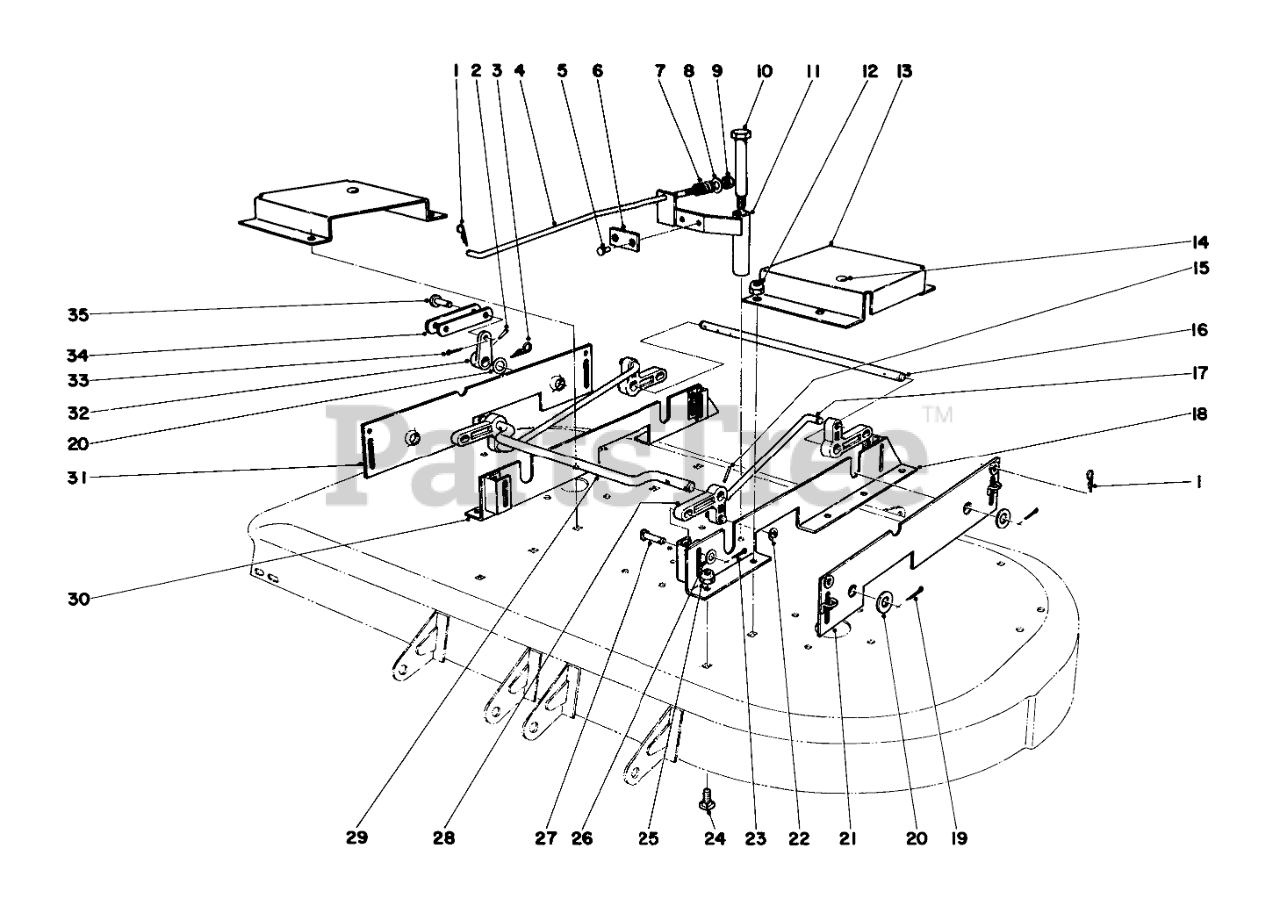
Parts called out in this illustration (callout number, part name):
1	PIN-COTTER, HAIR
2	Pin Drive
3	HAIRPIN COTTER
4	Brake Rod
6	BLADE BRAKE LINING
7	Spring
8	Washer
9	NUT-LOCK, CONE
10	Shoulder Bolt
11	a. Bracket
12	NUT-LOCK, CONE
13	Cover
14	Plug Button
15	PIN-SPRING
16	Rear Pivot Shaft
17	Lift Link
18	Bracket Assy. Lower
19	PIN-COTTER
20	Washer
21	Mower Plate Housing
22	RING-RETAINING, EXT
23	PIN-COTTER
24	Screw
25	NUT-LOCK, CONE
26	Washer
27	Lift Pin
28	Bell Crank
29	Front Pivot Shaft
30	Bracket Assy. Lower
31	Mower Plate Housing
32	Lever
33	PIN-COTTER
34	Adjusting Link
35	Pin
